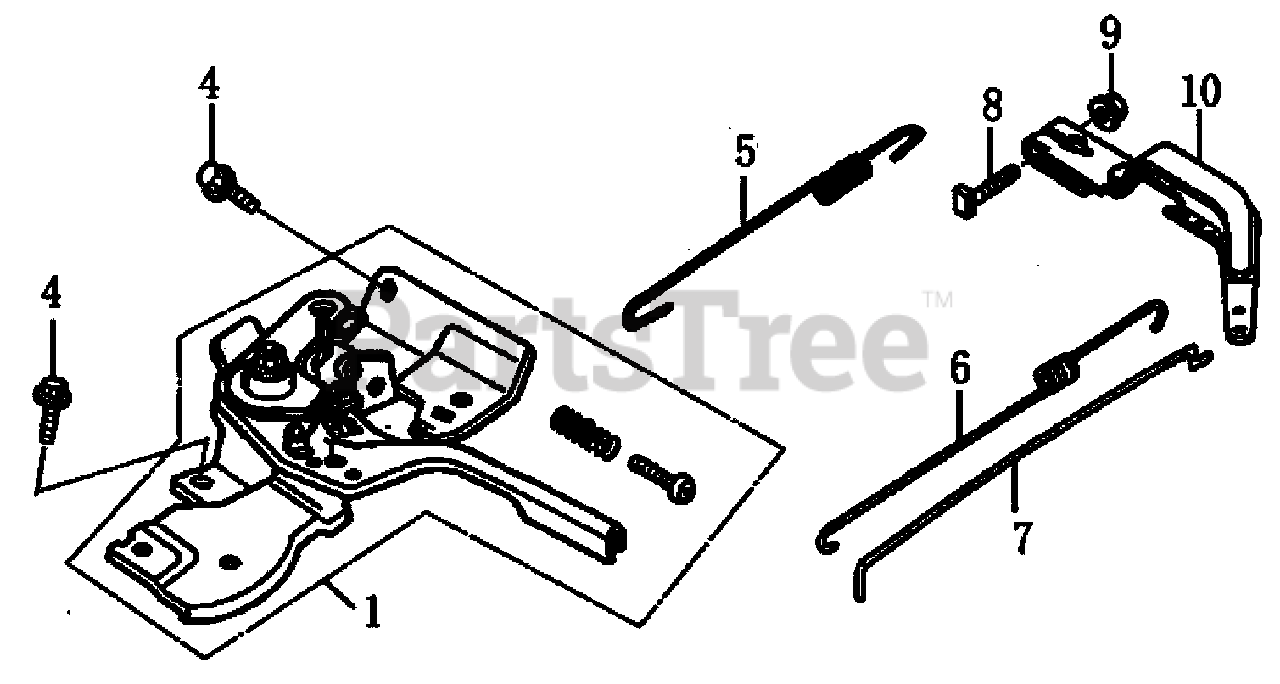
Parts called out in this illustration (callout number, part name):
1	CONTROL ASSY.
4	BOLT, FLANGE
5	SPRING, GOVERNOR
6	SPRING, THROTTLE RETURN
7	ROD, GOVERNOR
8	BOLT, QUADRATE HEAD
9	NUT, FLANGE
10	ARM, GOVERNOR
